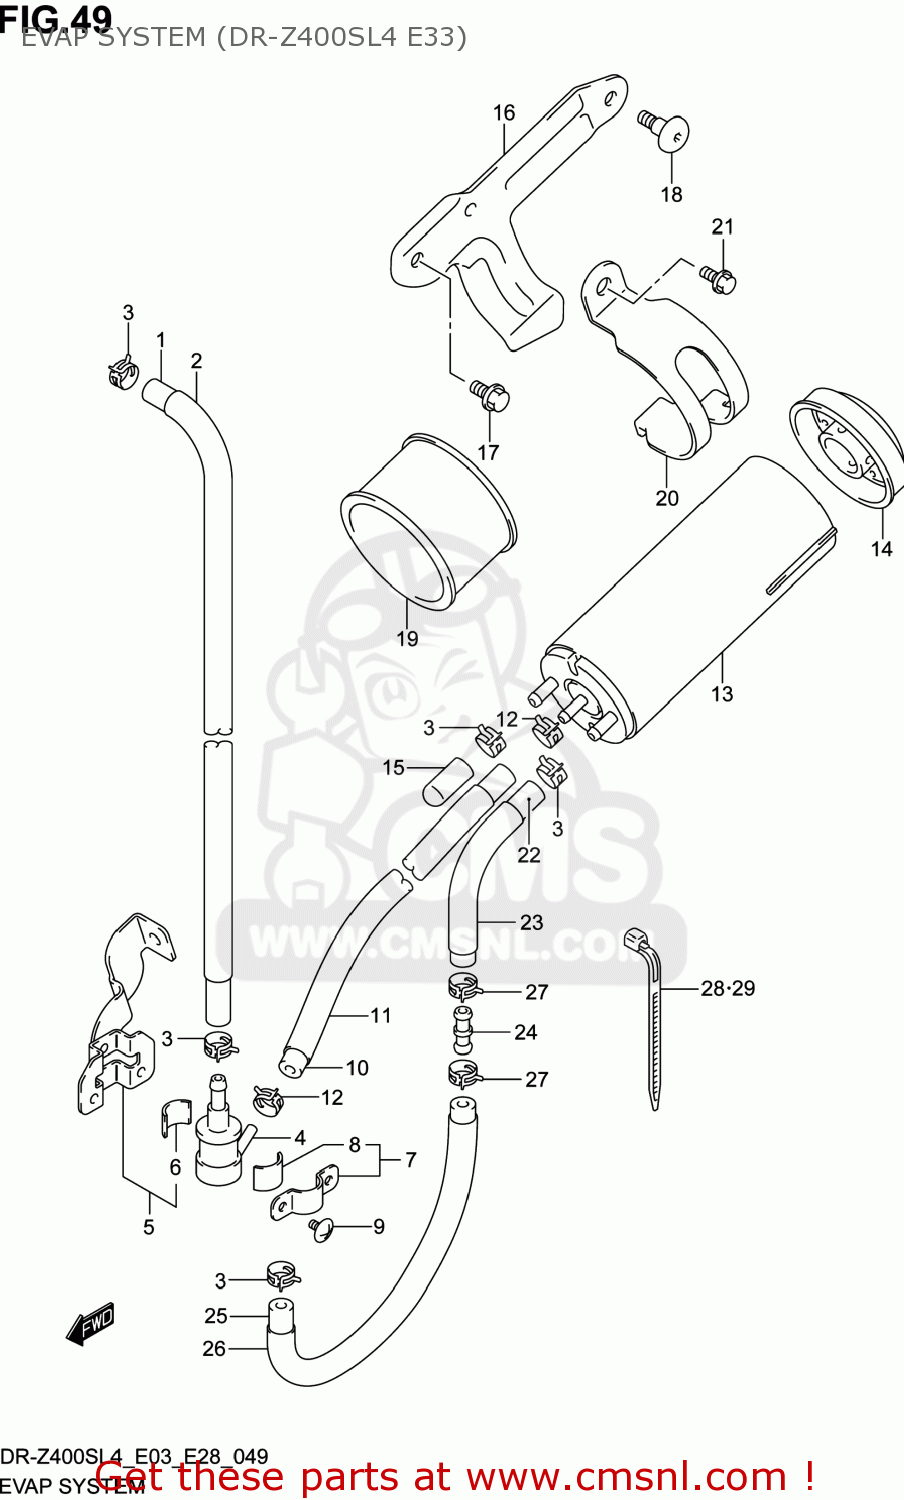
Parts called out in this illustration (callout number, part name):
1	HOSE,TANK & BREATHER VALVE
2	PROTECTOR(14.5X15.5X600)
3	CLIP
4	VALVE,FUEL TANK BREATHER
5	BRACKET,BREATHER VALVE
6	CUSHION
7	PLATE,FUEL TANK BREATHER NO.2
8	CUSHION
9	SCREW
10	HOSE,BREATHER VALVE & CANISTER
11	HOSE
12	CLIP
13	CANISTER ASSY,CHARCOAL
14	CAP,CANISTER
15	CAP,OD:11.5
16	BRACKET,CANISTER
17	BOLT
18	BOLT(6X16)
19	CUSHION,CANISTER
20	HOLDER,CANISTER
21	BOLT
22	HOSE,CSTR PURGE
23	PROTECTOR(14.5X15.5X600)
24	UNION
25	HOSE,CSTR & CARB PURGE NO.2
26	PROTECTOR(14.5X15.5X600)
27	CLIP
28	CLAMP(L:145)
29	CLAMP(L:125)
